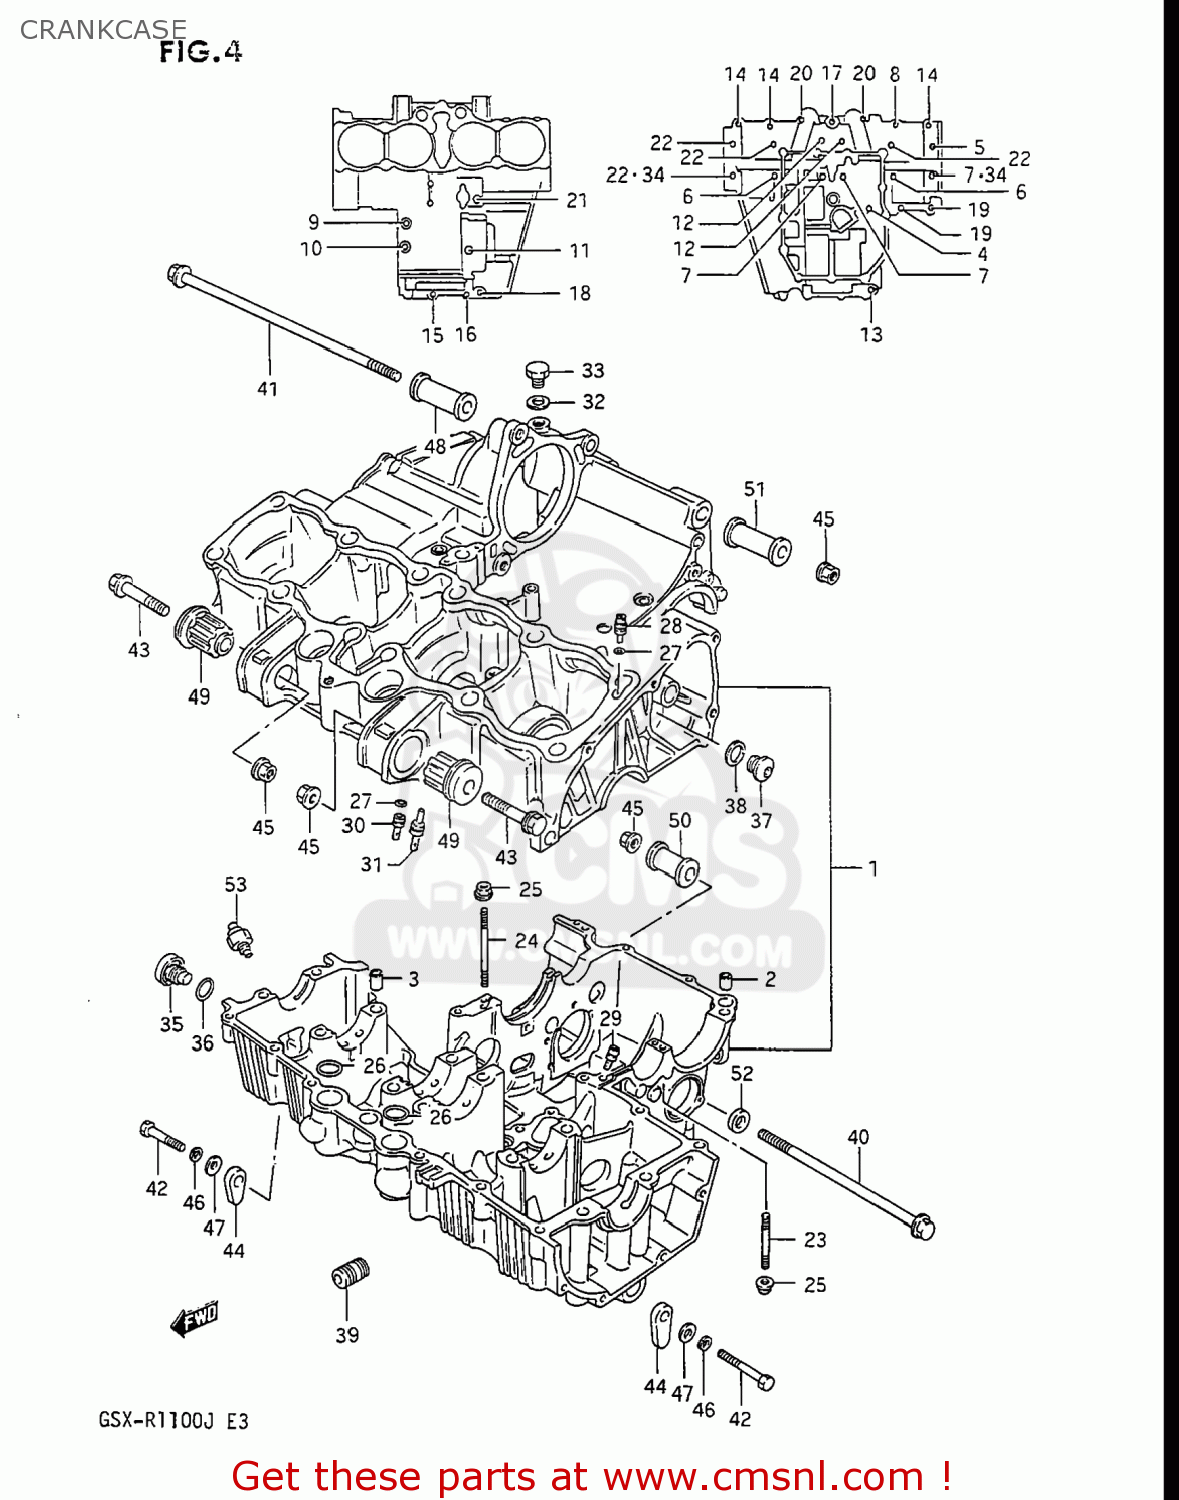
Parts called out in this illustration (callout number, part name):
1	CRANKCASE SET
2	PIN(10.4X13X22)
3	PIN (11X20)(SUS)
4	BOLT(6X105)
5	BOLT(8X105)
6	BOLT(8X125)
7	BOLT(8X115)
8	BOLT 6X35
9	BOLT
10	BOLT
11	BOLT
12	BOLT
13	BOLT 8X60
14	BOLT 6X35
15	BOLT
16	BOLT
17	BOLT 6X50
18	BOLT ,6X60
19	BOLT
20	BOLT
21	BOLT
22	BOLT(8X95)
23	STUD BOLT
24	STUD BOLT
25	NUT
26	O RING(D:2.5,ID:21)
27	O RING(D:1.2,ID:4)
28	JET,AIR
29	JET
30	JET,OIL
31	JET,OIL GALLERY
32	GASKET(12.1X16.2X3.7) (NAS)
33	PLUG(12X9)
34	GASKET(8.5X17X2.3) (NAS)
35	PLUG
36	O RING(D:2.4,ID:16.8)
37	PLUG
38	GASKET(14X19.2X2) (NAS)
39	UNION,OIL STAND
40	BOLT(10X180)
41	BOLT(10X255)
42	BOLT 10X55
43	BOLT 10X55
44	NUT
45	NUT
46	WASHER,LOCK,10
47	WASHER
48	SPACER,ENGINE MOUNT (L:
49	BUSH,ENGINE MOUNTING
50	SPACER,ENGINE MOUNT
51	SPACER,ENGINE MOUNT (L:
52	SPACER
53	SWITCH ASSEMBLY
